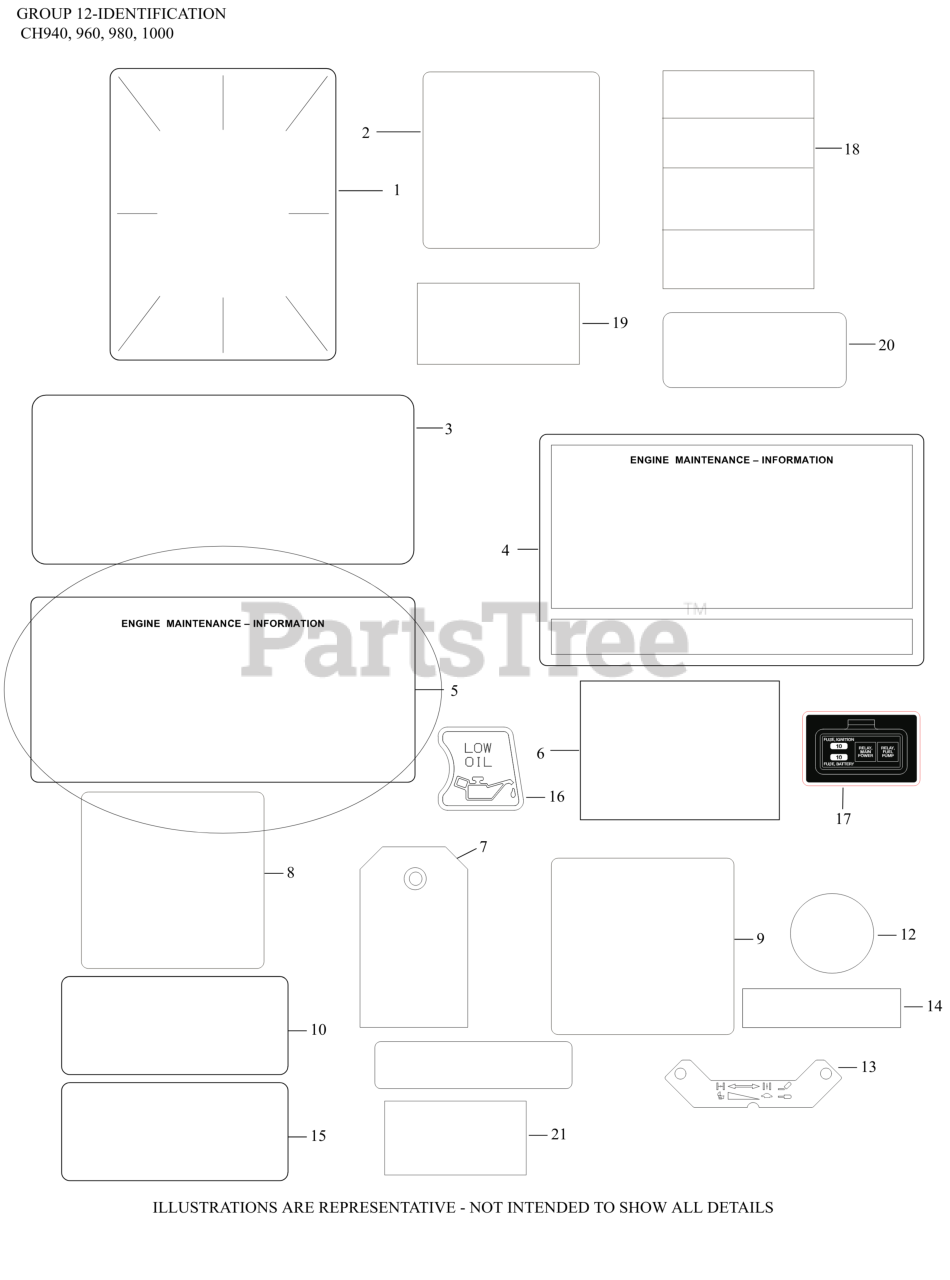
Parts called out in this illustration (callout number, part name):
1	LABEL, CLEAR LAMINATION
8	DECAL, 35 HP/999cc/CV-CH1000
12	LABEL, GRASS SCREEN
